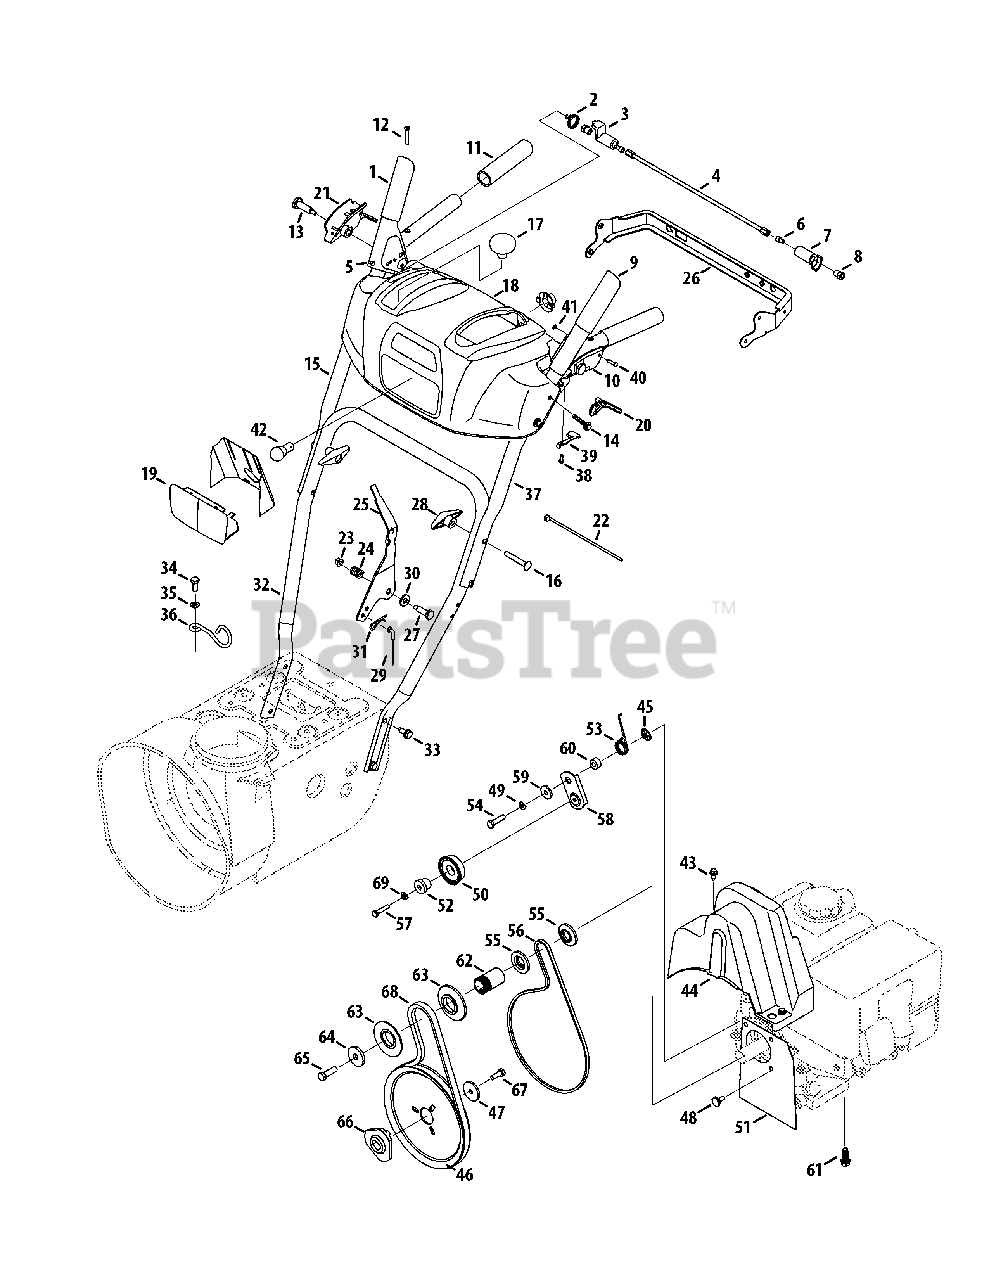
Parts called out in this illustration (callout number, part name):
1	Handle Engagement Ass’y RH
2	Torsion Spring
3	Lock Plate
4	Pivot Rod
5	Rubber Bumper
6	Screw, 1/4-20 x .500
7	Clutch Lock Cam
8	Shoulder Nut, 1/4-20
9	Handle Engagement Assembly LH
10	Handle Clutch Lock LH Assembly
11	Handle Grip
12	Screw, #10-24 x 0.375
13	Shoulder Screw, 1/4-20
14	Screw, 1/4-20 x 1.625
15	Upper Handle RH
16	Carriage Screw, 5/16-18 x 2.25
17	Shift Knob
18	Handle Panel
20	Steering Control
21	Handle Clutch Lock RH Assembly
22	Cable Tie
23	Flange Lock Nut, 1/4-20
24	Compression Spring
25	Shift Lever
26	Panel Bracket
27	Shoulder Screw
28	Wing Knob
29	Speed Selector Cable
30	Flat Washer
31	Click Pin
32	Lower Handle
33	Screw, 5/16-18 x 0.75
34	Screw, M8-1.25
35	Flat Washer, .330 x .630 x .0635
36	Cable Control Wire
37	Upper Handle LH
38	Screw, #8-16 x 0.50
39	Clutch Lock Spring
40	Pin, 3/16
41	Retainer Ring
42	Light Bulb
43	AB Screw, 1/4-20 x 0.625
44	Belt Cover
45	Push-on Nut
46	Auger Pulley
47	Flat Washer
48	Shoulder Screw
49	Lock Washer
50	Idler Pulley Assembly
51	Plt., Cvr.
52	Spacer
53	Torsion Spring
54	Hex Screw, 5/16-24 x 1.25
55	Pulley Half
56	Belt, Wheel Drive
57	TT Screw, 1/4-20 x 1.25
58	Drive Clutch Idler Bracket
59	Shoulder Spacer
61	TT Sems Screw, 3/8-16 x 1.0
62	Spacer
63	Pulley Half
64	Flat Washer
65	Hex Bolt, 3/8-24 x 1.25
66	Pulley Adapter
67	Hex Bolt, 5/16-24 x 0.875
68	V-Belt,.500 x 35.00 Lg
